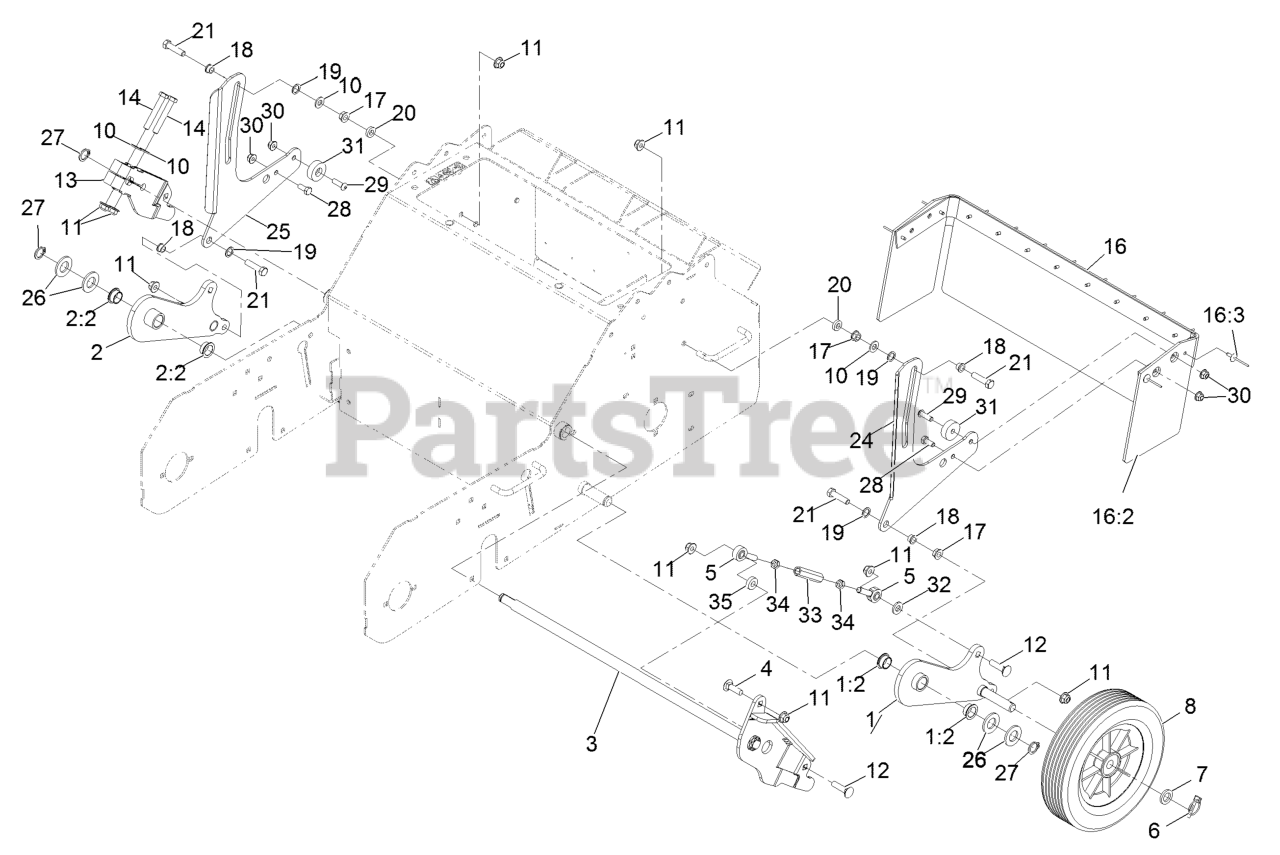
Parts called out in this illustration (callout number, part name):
1	WHEEL ARM ASM-LH W/BRGS
1:2	BUSHING-BRONZE
2	WHEEL ARM ASM-RH W/BRGS
2:2	BUSHING-BRONZE
3	SHAFT-PIVOT
4	BOLT-CARR
5	BALLJOINT
6	PIN-KLIK
7	SPACER-BEARING
8	WHEEL-TRANSPORT 10"
10	WASHER-FLAT
11	NUT-HF, NI
12	SCREW-CARR
13	ARM-LIFT, RH
14	BOLT-CARR
16	GUARD-FOOT
16:2	FOOT-SHIELD
16:3	RIVET-POP
17	NUT-HHF, WHIZ
18	BUSHING-FLANGED
19	WASHER-NYLON
21	SCREW-HH
24	GUARD-ARM, LH
25	GUARD-ARM, RH
26	WASHER-FLAT
27	RING-RETAINING
28	SCREW-HH
29	SCREW-HSBH
30	NUT-HF, NI
31	GUIDE-ARM, TRAIL
33	ROD-LIFT LINK
34	NUT-HJ
35	SPACER
